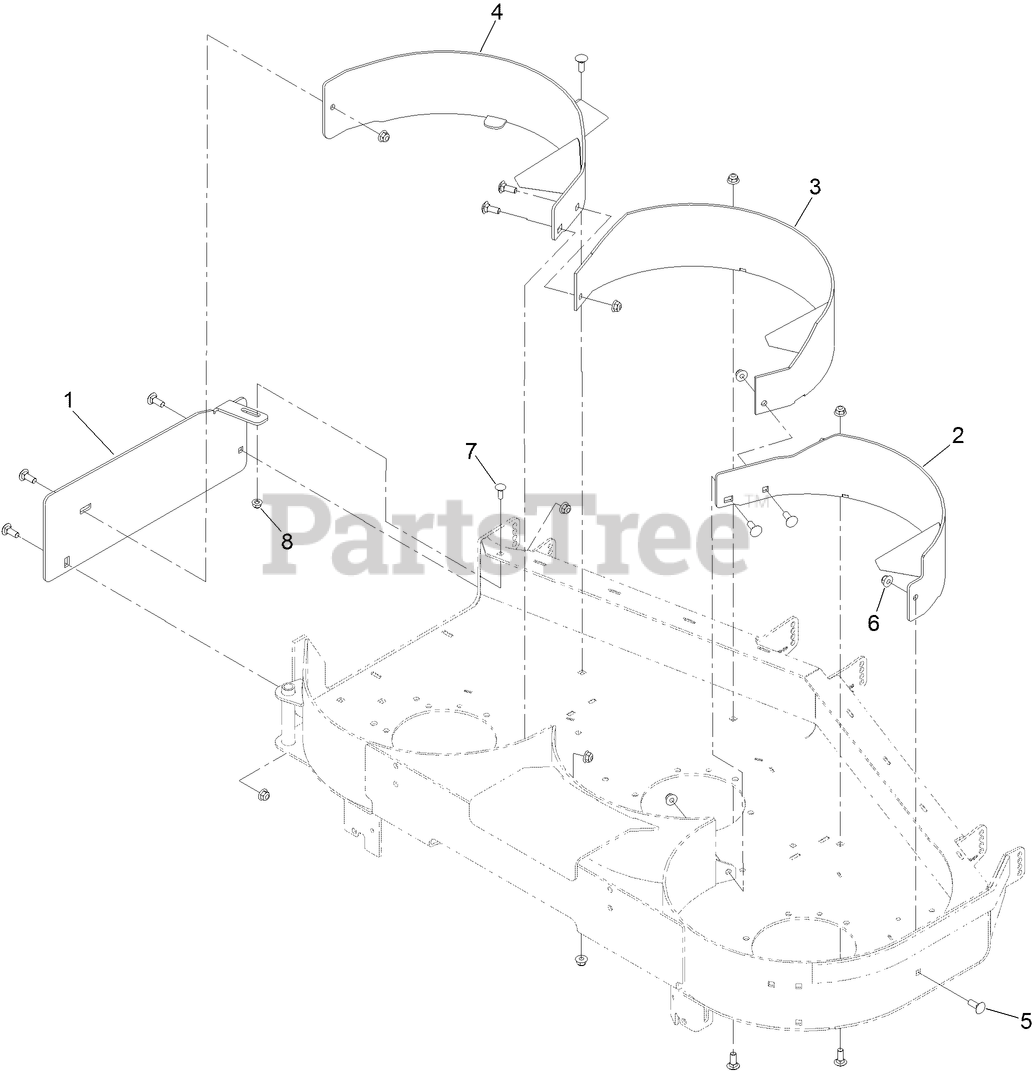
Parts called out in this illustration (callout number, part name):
1	PLATE-COVER, DISCHARGE
2	BAFFLE-LH
3	BAFFLE-CENTER
4	BAFFLE ASM-RH, 52
5	BOLT-CARR
6	NUT-HF, NI
7	SCREW-CARR
8	NUT-HF, NI
